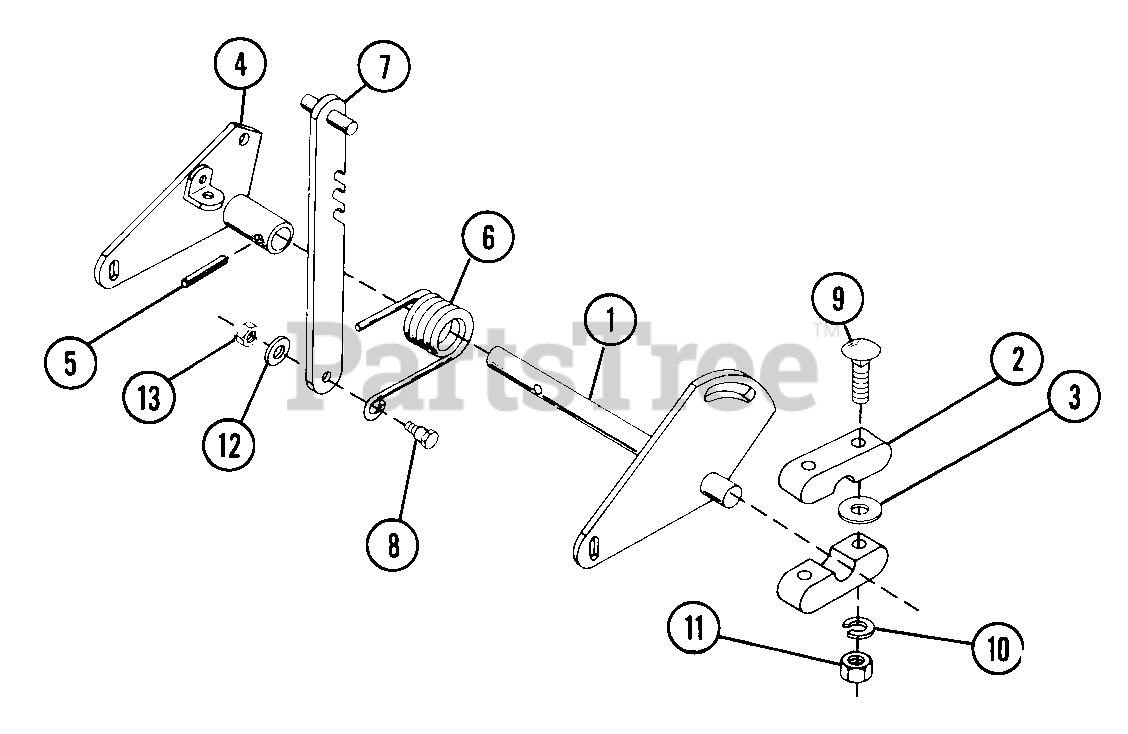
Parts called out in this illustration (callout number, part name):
1	CENTER ROCK SHAFT
3	WSHR-FL-STL .406X.750X.005
4	R H ROCKSHAFT LEVER
5	PIN-GRV .250X2.00
6	SG-TORS .312X1.38X2.031
7	SPRING HANDLE
8	SHOULDER BOLT .50 X .31
9	BLT-RDHDSQNK .38-16X2.25 SHTPL
10	WSHR-LK .375X.094 MED PL
11	NUT-HEX .375-16
12	WSHR-FL-STL .531X1.062X.095 PL
13	NUT-LK-CTR .375-16 GR A PL
